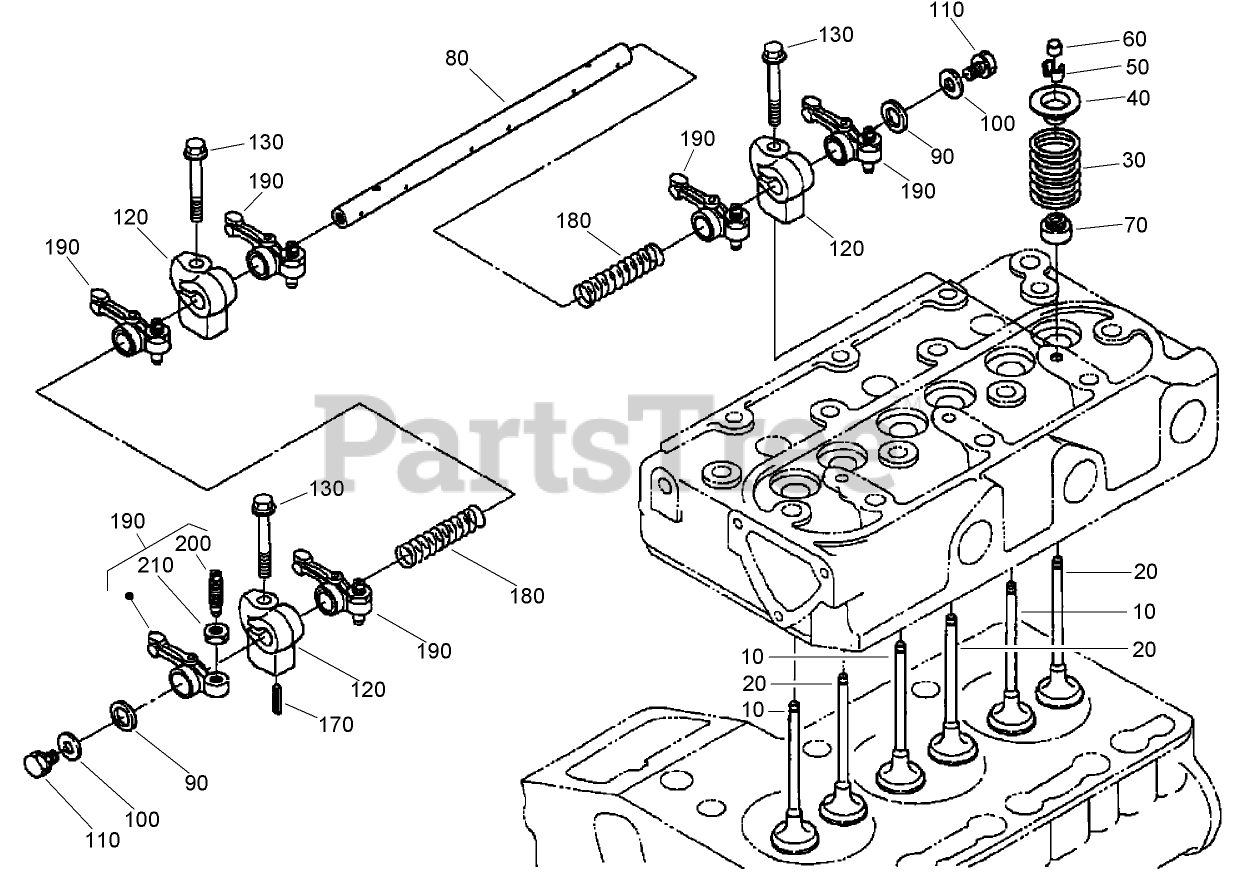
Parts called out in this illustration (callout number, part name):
10	VALVE-INLET
20	VALVE-EXHAUST
30	SPRING-VALVE
40	RETAINER-SPRING, VALVE
50	COLLET-SPRING, VALVE
60	CAP-VALVE
70	SEAL-STEM, VALVE
80	SHAFT-ARM, ROCKER
90	WASHER
100	WASHER-PLAIN
120	BRACKET-ARM, ROCKER
130	BOLT-FLANGE
170	PIN-SPRING
180	SPRING
190	ROCKER ARM ASM
200	SCREW-ADJUSTING
